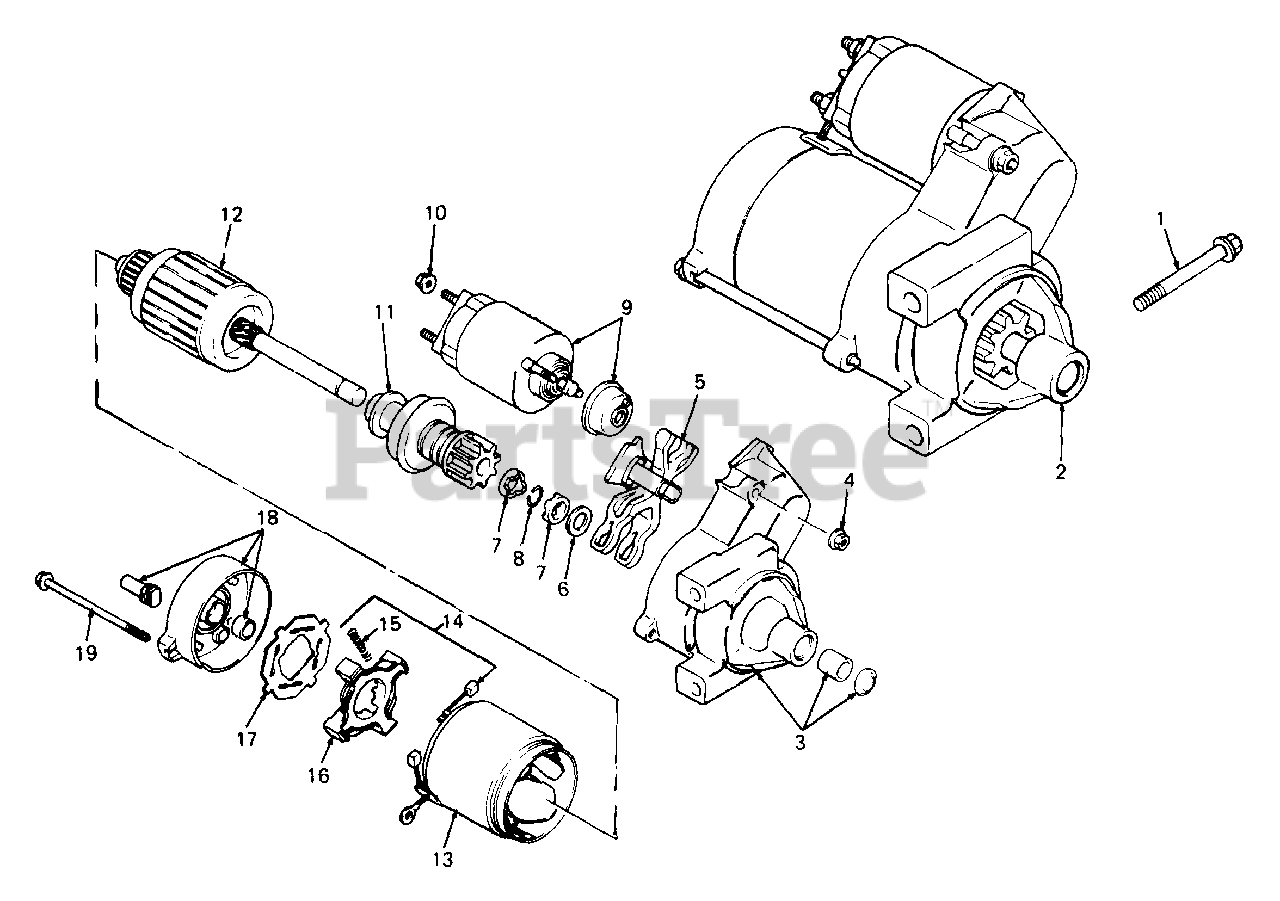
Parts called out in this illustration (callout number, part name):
1	Screw, M8 X 1.25 X 80.6
2	Starter Assy, Solenoid Shift
3	Cap, Drive End
4	Nut, Starter
5	Lever, Starter Drive
6	Washer, Thrust
7	Nut, Stop Collar
8	Ring, Retainer
11	Drive, Pinion
14	Kit, Brush
15	Spring, Brush
16	Holder, Brush
18	Cap, Commutator End
